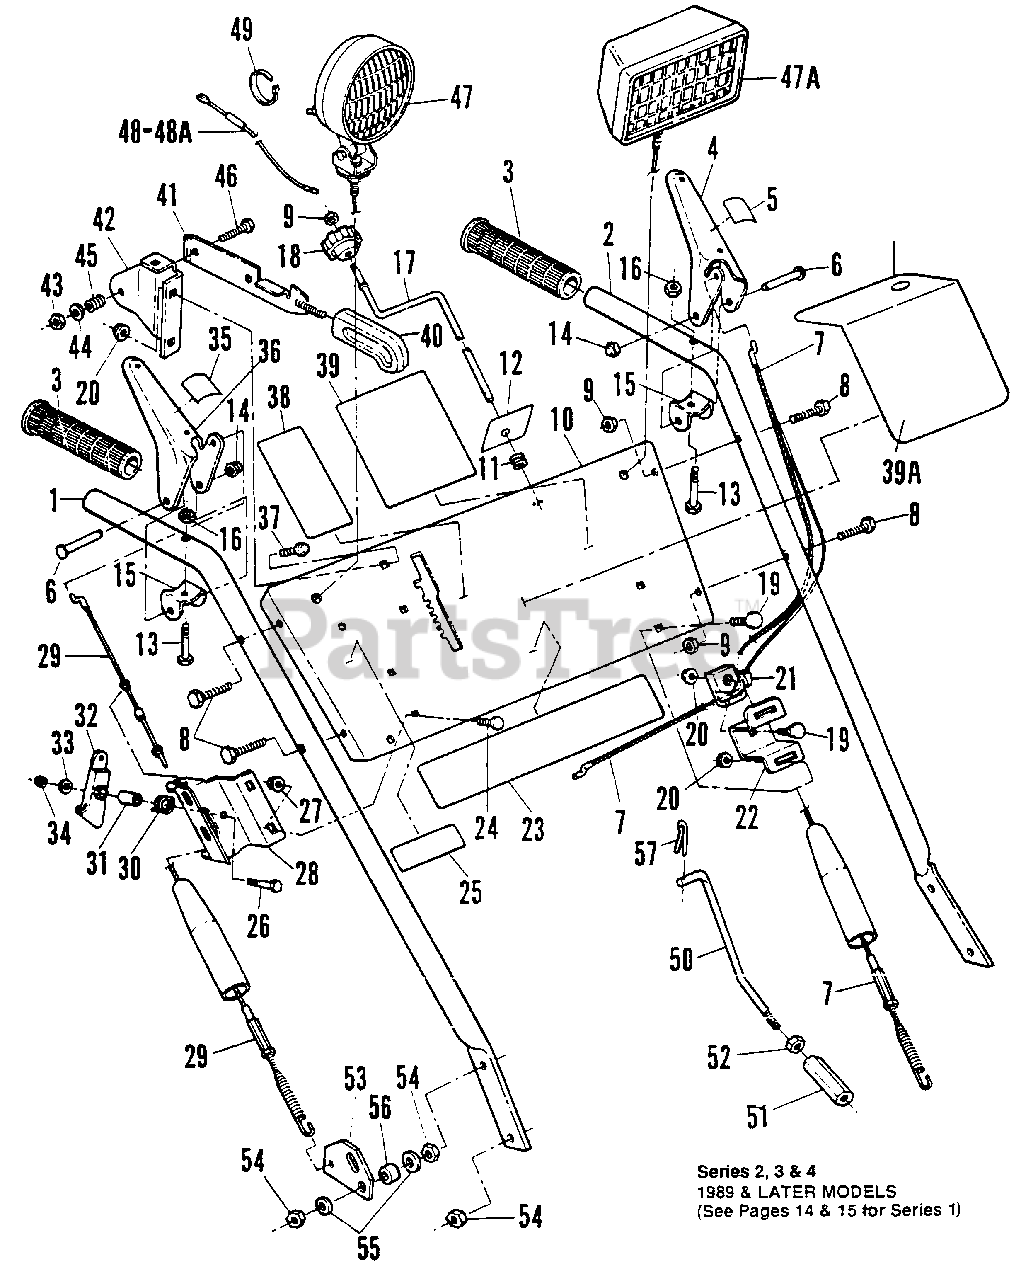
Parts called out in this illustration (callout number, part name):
1	BAR, Handle
2	BAR, Handle
3	GRIP, Handle
4	HANDLE, Left Side
5	DECAL, Traction Clutch
6	PIN, 1/4 x 1-7/8" Clevis
7	CABLE, Left Side Clutch
8	SCREW, 5/16-18 x 1-1/2" Hex Head Cap
9	NUT, 5/16-18 Hex Center Lock
10	PANEL, Control
11	BUSHING
12	DECAL, Chute Control
13	SCREW, 1/4-28 x 1-3/8" Hex Head Cap
14	NUT, 1/4 Push
15	BRACKET, Handle
16	NUT, 1/4-28 Hex Top Lock
17	CRANK, Chute
18	KNOB, Chute Crank
19	BOLT, 1/4-20 x 3/4" Carriage
20	NUT, 1/4-20 Hex Flange Lock
21	GUIDE, Cable
22	BRACKET, Cable Guide Support
23	DECAL, SNAPPER
24	BOLT, #10-24 x 1/2" Hex Flange Lock
25	DECAL, 824
26	SCREW, 1/4-20 x 1" Hex Head Cap
27	NUT, #10-24 Hex Flange Lock
28	BRACKET
29	CABLE, Auger
31	SPACER
32	LOCK, Cam
33	WASHER, 1/4 Flat
34	NUT, 1/4-20 Hex Center Lock
35	DECAL, Blower Clutch
36	HANDLE, Right Side
37	BOLT, 1/4-20 x 1/2" Short Neck Carriage
38	DECAL, Direction Control
39	DECAL, Instruction
39A	DECAL, Instruction 826
40	KNOB, Shift Handle
41	HANDLE, Shift
42	BRACKET, Shift Lever
43	NUT, 5/16-24 Hex Center Lock
44	WASHER, 5/16 Flat
45	SPRING
46	SCREW, 5/16-24 x 1-1/4" Hex Head Cap
47	ASSEMBLY, Light
47A	ASSEMBLY, Light
48	HARNESS, Wiring
48A	HARNESS, Wiring
49	TIE, Cable
50	ROD, Upper Shift
51	NUT, 3/8-16 x 1-13/16 Connector
52	NUT, 3/8-16 Hex
53	LEVER, Clutch
54	NUT, 5/16-18 Hex Flange Lock
55	WASHER, 5/16" x 1-1/4" x 3/32" Flat
56	SPACER, 5/16
57	PIN, 1/8 x 1" Cotter
